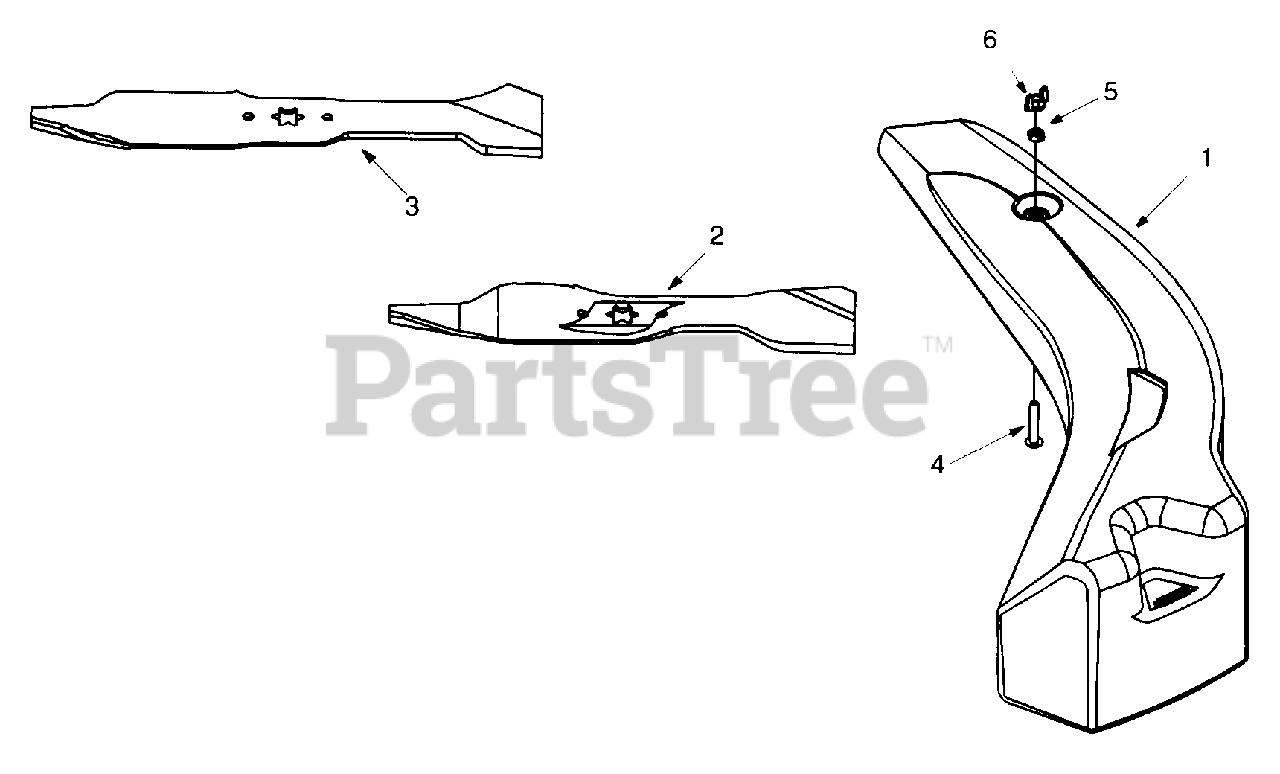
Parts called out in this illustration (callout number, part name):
2	Mulching Blade: 14.88" Lg.
3	Mulching Blade: 16.28" Lg.
4	Machine Screw 1/4"
5	Lock Nut 1/4" Thd.
